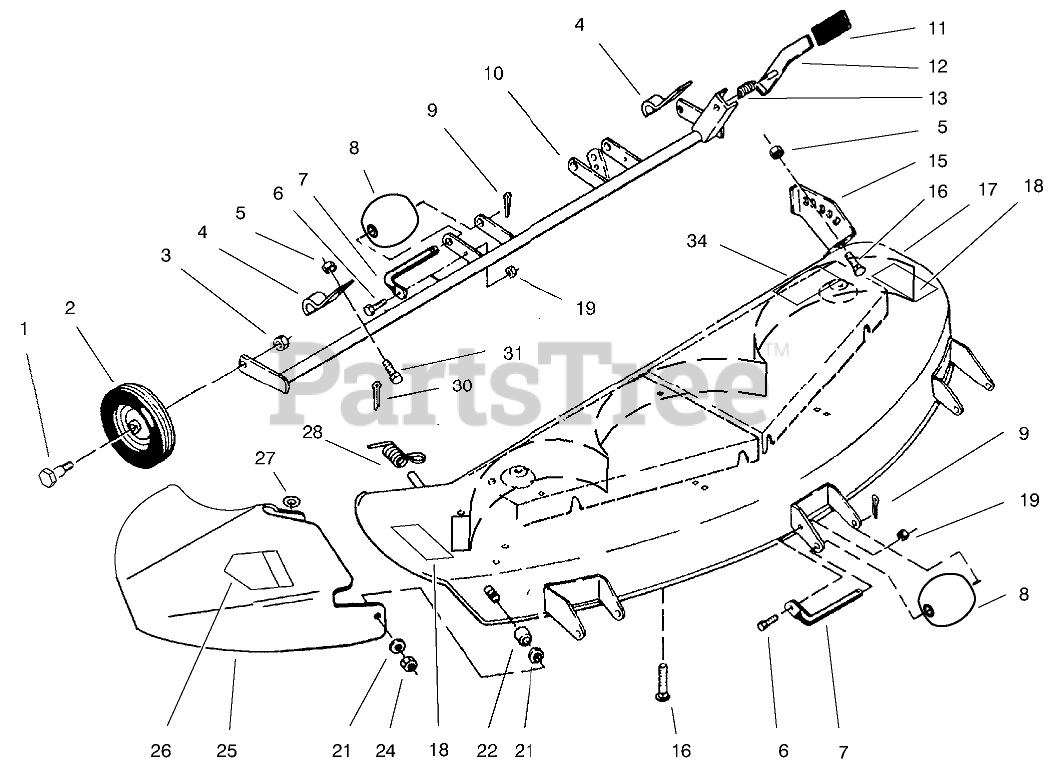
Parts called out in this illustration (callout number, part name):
1	BOLT-SHOULDER
2	WHEEL
3	NUT-HEX
4	BRACKET-PIVOT
5	NUT-LOCK, NI
6	SCREW-HH
7	ROLLER-SHAFT
8	ROLLER
9	PIN-COTTER
10	WA-SUPPORT,GAGE WHL (RED)
12	WLDMT-LEVER (RED)
13	SPRING-COMPRESSION
15	RH QUADRANT (RED)
16	BOLT-CARR
17	Deck-Assembly (Incl. Ref. #18)
18	DECAL-DANGER
19	NUT-LOCK, NI
21	WASHER
22	BUSHING-PIVOT
24	NUT-HJ
25	Chute Assembly (Incl. Ref. #26)
26	DECAL-DANGER
27	WASHER-FLAT
28	SPRING-DEFLECTOR
30	PIN-COTTER
31	BOLT-CARR
34	DECAL-HEIGHT & BELT
